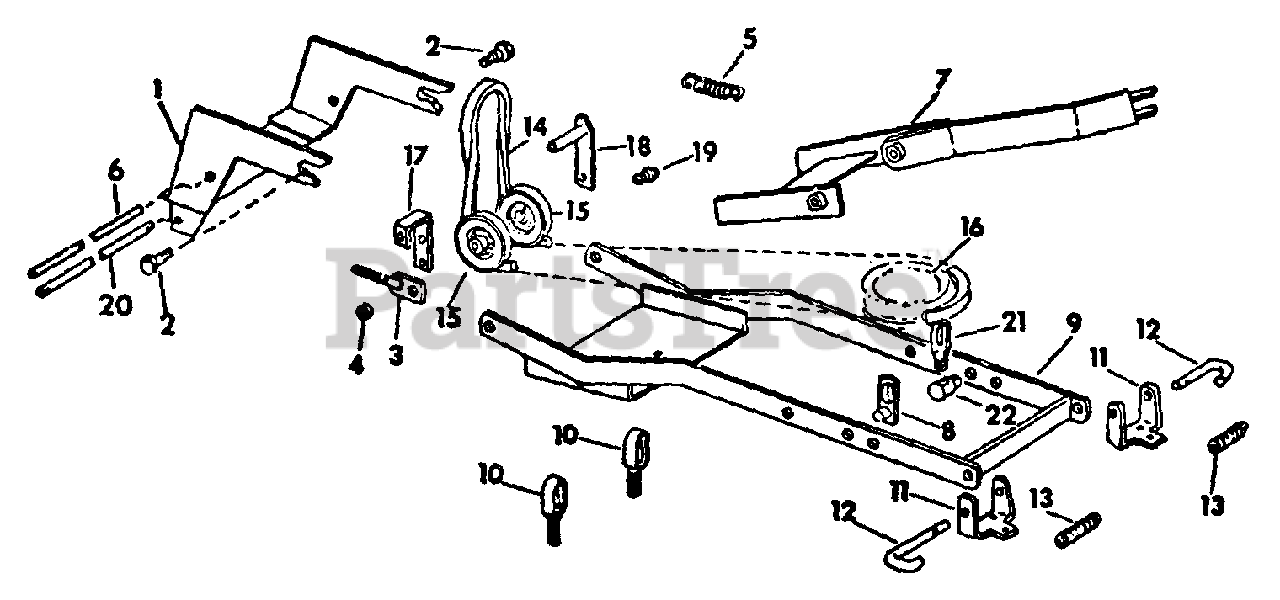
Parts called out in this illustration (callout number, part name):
1	HANGER ASSY, FRONT
2	NOT USED IN THIS APPLICATION
3	BRACKET ASSY, IDLER ADJUSTING
4	SPACER IDLER ADJUSTING
5	SPRING, MULE DR. EXTENSION
6	SHAFT, IDLER PIVOT
7	FRAME ASSY, CENTER
8	LINK ASSY, LIFT
9	FRAME ASSY, OUTER LIFT
10	HANGER, MOWER SUPPORT FRONT
11	BRACKET, MOWER SUPPORT
12	PIN, MOWER SUPPORT
13	SPRING, MOWER SUPPORT PIN
14	BELT, MULE DRIVE
15	PULLEY, DRIVE BELT IDLER
16	PULLEY, CENTER
17	ARM, IDLER LH
18	ARM ASSY, IDLER RH
19	SPACER, SPRING
20	SHAFT FRONT HANGER
21	LINK, ADJUSTABLE
22	BLOCK, ADJUSTING
18481-R1	PIN, 3/16 x 1 C-Z COTTER
18481-R1	PIN 16 x 1 C-Z COTTER
180134	SCREW, 3/8-16 x 2-1/2 ZND HEX-HD CAP
